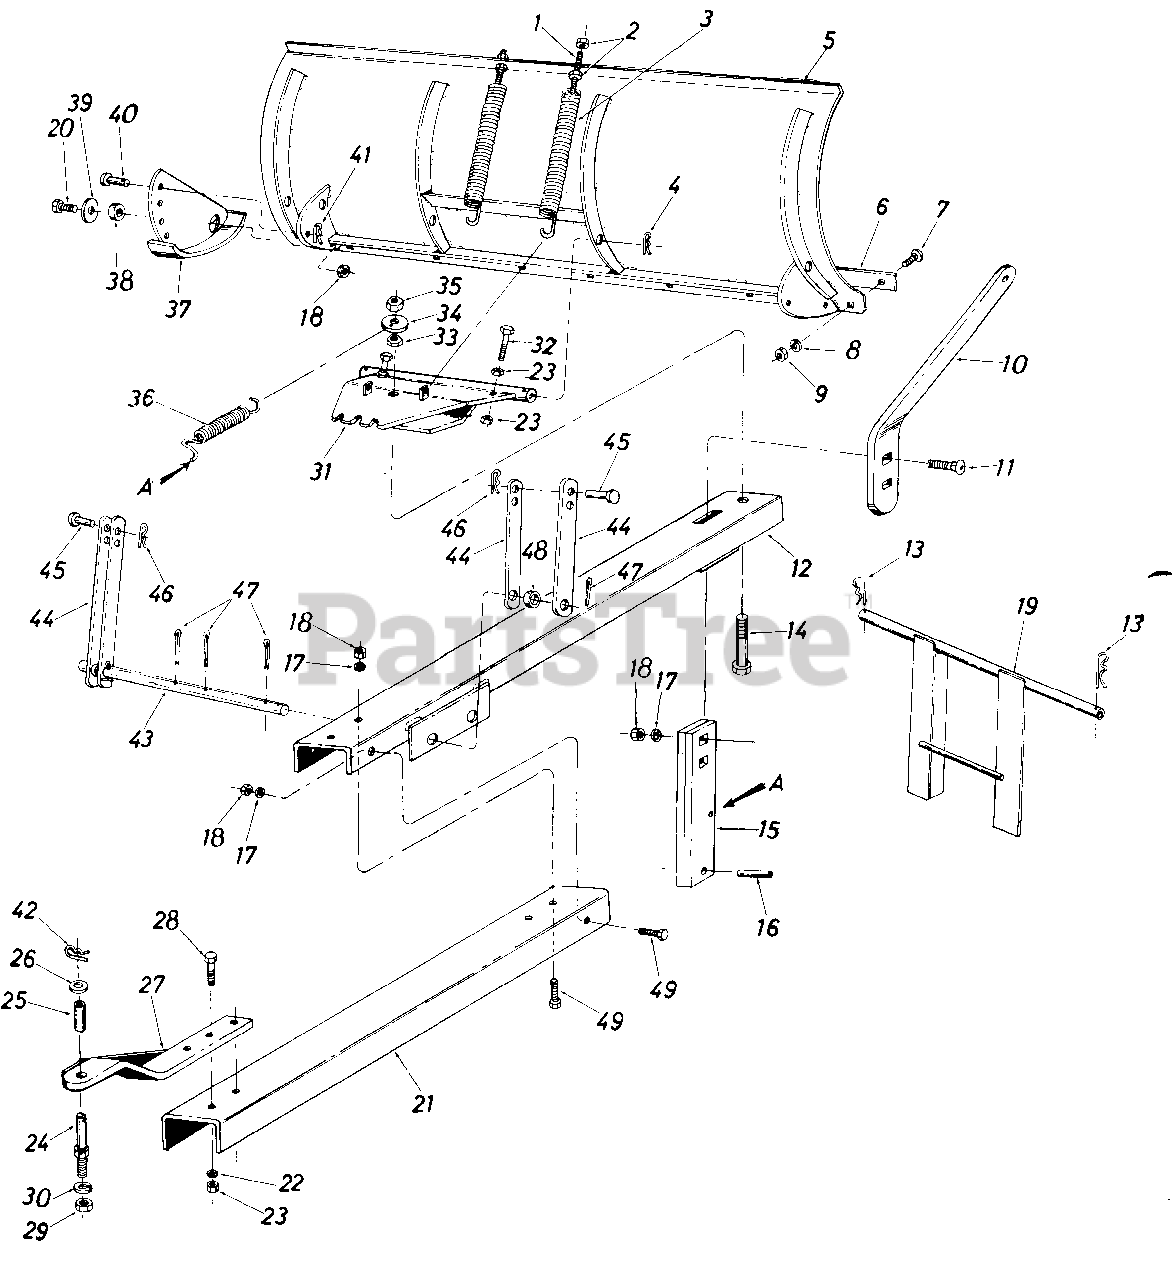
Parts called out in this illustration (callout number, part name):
1	Hex Scr. 3/8-16 x 4.50" Lg.*
2	Hex Nut 3/8-16 Thd.*
3	Blade Adjustment Spring
4	Hair Pin Cotter, 5/32
5	54" Blade Ass'y.
6	Wear Plate
7	Carriage Bolt 5/16-18 x .75" Lg.*
8	L.-Wash. 5/16" Scr.*
9	Hex Nut 5/16-18 Thd.*
10	Lock Extension Bar
11	Carriage Bolt 3/8-16 x 1.25" Lg.
12	Front Push Bar Ass'y.
13	Hair Pin Cotter, 5/32
14	Hex Scr. 3/4-10 x 3.50" Lg.*
15	Angle- Lock Bar
16	Spring Pin Spirol .25" Dia. x 1.00" Lg.
17	L.-Wash. 3/8" Scr.*
18	Hex L.-Nut 3/8-1 Thd.*
19	Guide Bracket Ass'y.
20	Hex Scr. 3/8-16 x .75" Lg.*
21	Rear Push Bar Channel
22	L.-Wash. 1/2" Scr.*
23	Hex Nut 1/2-13 Thd.*
24	Link Clevis Pin
25	Spacer 1" O.D. x 21/32" I.D. x .75" Lg.
26	Fl-Wash. 21/32 I.D. x .090 O.D.
29	Hex Jam L.-Nut 5/8-18 Thd.
30	L.-Wash. 5/8" Scr.*
31	Pivot Plate Ass'y.
32	Hex Scr. 1/2-13 x 2.00" Lg.*
33	Hex Jam Nut 3/4-10 Thd.
34	Fl.-Wash. 3/8"
35	Hex Lock Nut 3/4-10 Thd.
36	Angle Lock Spring
37	Skid Assembly
38	Bushing, Pivot Skid
39	Fl.-Wash. .385" I.D. x 1.00" O.D.
40	Clevis Pin 5/16" Dia. x 3/4" Lg.
41	Hair Pin Cotter 3/32"
42	Hair Pin Cotter, 5/32
43	Lift Shaft
44	Lift Link
45	Clevis Pin 1/2" Dia. x 1.00" Lg.
46	Hair Pin Cotter, 3/32"
47	Cotter Pin 1/8" Dia. x 1.50." Lg.*
48	Spacer, Lift Link
49	Hex Scr. 3/8-16 x 1.00" Lg.*
